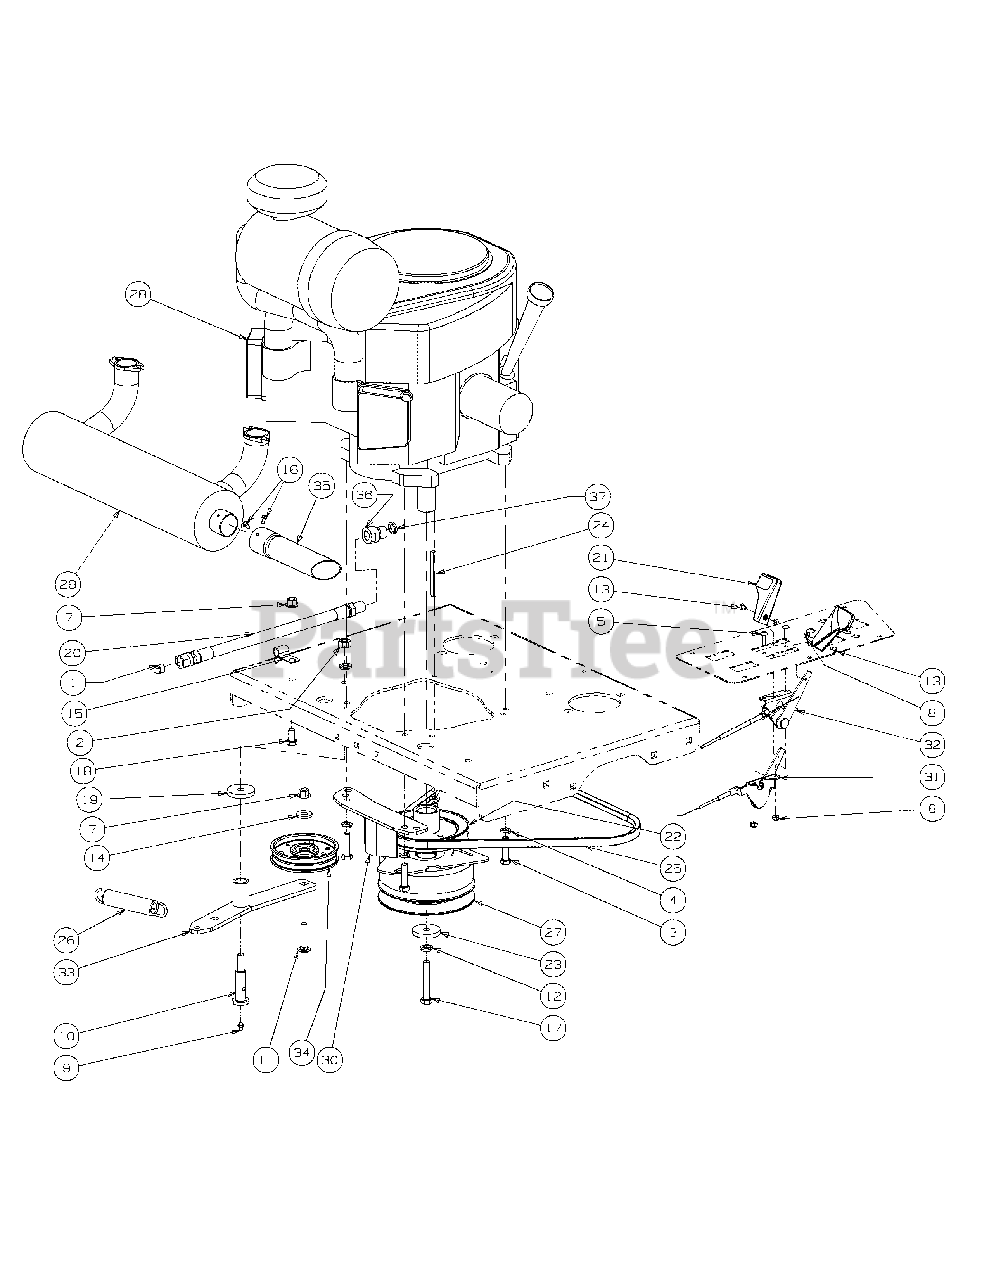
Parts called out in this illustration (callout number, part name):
1	Pipe Plug, 3/8 NPT
2	Hex Nut, 7/16-14
3	Hex Head Cap Screw, 3/8-16 x 1.50
4	Washer lock 3/8 zinc
5	Round Hd. Machine Screw, 10-32 x 3/4
6	Lock Nut, Nylon Insert, 10-32
7	Flange Lock, Hex Nut, 3/8-16
8	Nut Washer, W/Star, 8-32
9	Grease Fitting, 1/4-28 x 3/16
10	Shoulder Screw, 7/16-14
11	Hex Carriage Screw, 3/8-16, 1.75
12	Lock Washer, 7/16
13	Machine Screw, 8-32, .375
14	Flat Washer, .406 ID, 1.0 OD, .105
15	Clip, Heat Shield Cable
16	Screw, #8-32 x .375
17	Capscrew, 7/16-20 x 2.50
18	Hex Cap Screw, 3/8-16, .750
19	Flat Washer, 7/16 ID x 1.75 OD x .25
20	Oil Drain Hose
21	Control Throttle Knob
22	Pump Drive Pulley
23	Flat Washer, 7/16 ID x 1.75 OD x .25
24	Key, 1/4 x 1/4 x 3
25	Belt, 51.2 Lg
26	Extension Spring, .98 OD x 5.00
27	Clutch Brake, 1.125 ID
28	Engine, 37HP Kawasaki
29	Muffler, Kawasaki
30	Retainer Clutch Assembly
31	Throttle, Control Cable
32	Choke, Control Cable
33	Engine Idler Arm includes:
33	Bearing
34	Flat Pulley with Flanges
35	Muffler Accessory Exhaust Tube
36	Oil Drain Adaptor
